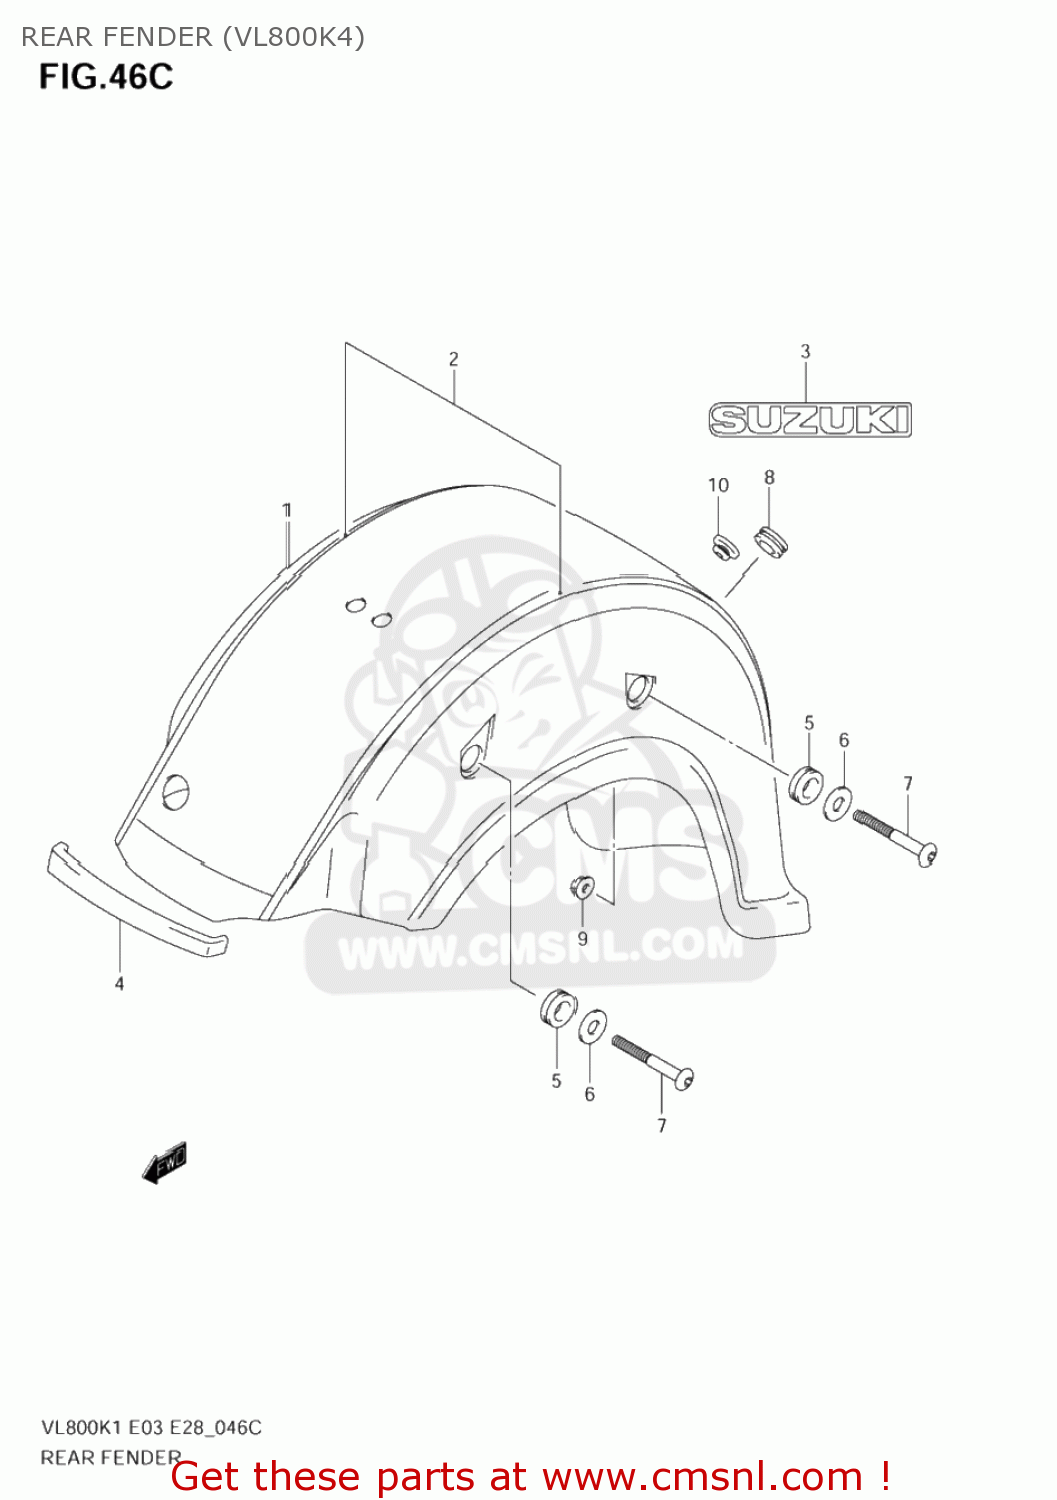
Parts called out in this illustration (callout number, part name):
1	FENDER,RR
2	TAPE SET,RR FENDER
3	EMBLEM
4	SEALER,SIDE COVER L
5	CUSHION,FRAME COVER UPR RR
6	WASHER(15.5X26X2.3)
7	BOLT,RR FENDER
8	CUSHION
9	NUT
10	CUSHION
